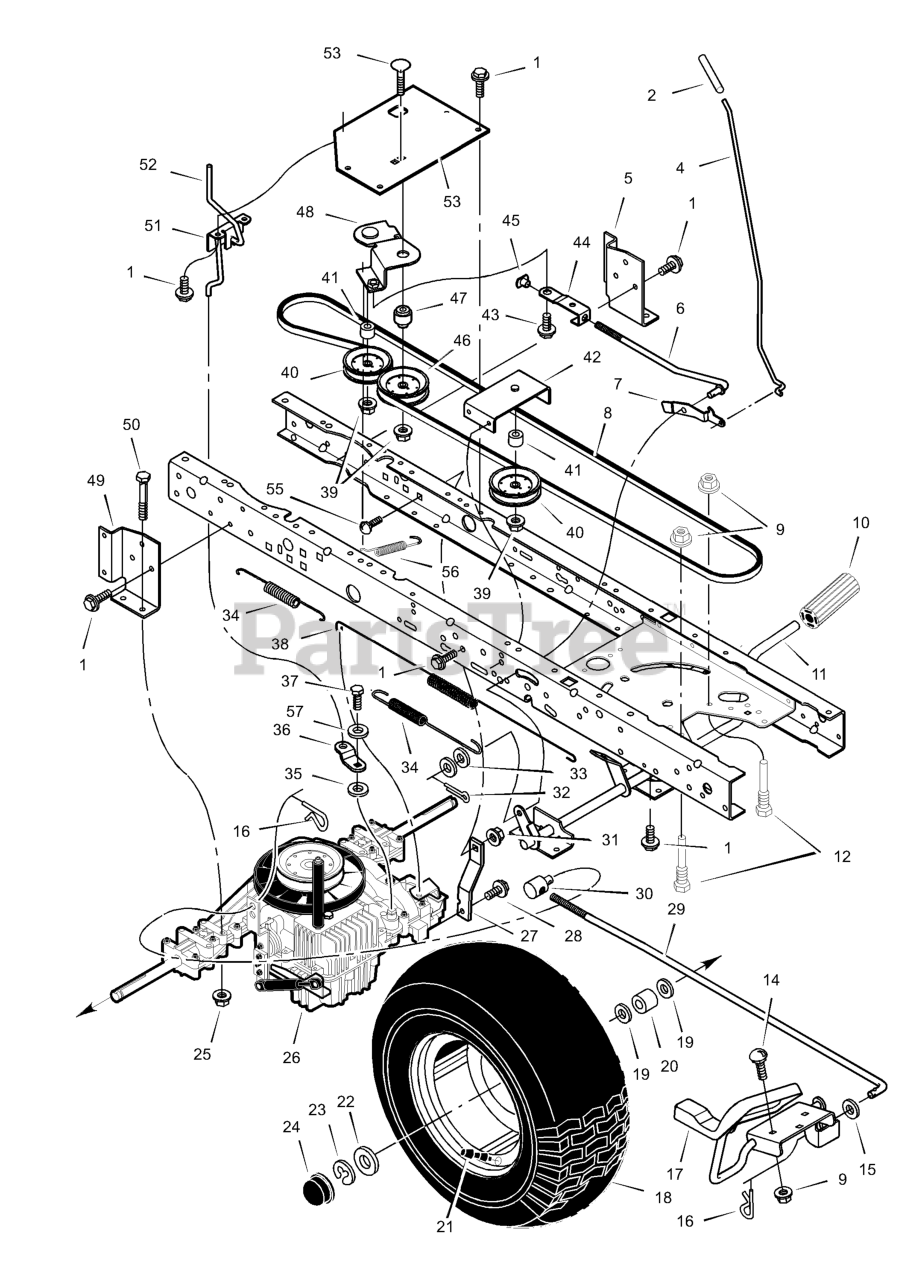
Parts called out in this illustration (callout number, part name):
2	Grip, Parking Brake
4	Rod, Parking Brake
5	Bracket, Left Transaxle
6	Rod, Clutch
7	Latch, Parking Brake
8	V-Belt, Drive
9	Nut, Flange
10	Pedal, Brake/Clutch
11	Assembly, Brake Pedal
12	Screw, Guide
14	Bolt, Carriage
16	Pin, Hair
17	Pedal Assembly, Hydro
18	Wheel & Tire Ass'y, Rear
20	Spacer
21	Stem, Valve
24	Cap, Hub
25	Nut, Centerlock
26	Transaxle **
27	Strap, Torque
29	Rod, Control
30	NUT, Adjusting, 1/2-13
31	Nut, Centerlock
32	Pin, Cotter
34	Spring, Extension
36	ARM, Disconnect
37	Capscrew
38	Spring, Brake
39	Locknut, Flange
40	Pulley, Idler
42	Bracket, Idler Assembly
43	Bolt, Shoulder
44	Link, Clutch
45	Nut, Tee
46	Pulley, Idler
47	Bushing, Pivot
48	Arm Assembly, Idler
49	Bracket, Right Transaxle
50	Bolt, Hex
51	Bracket, Disconnect
52	Rod, Disconnect
53	Bracket, Idler Pivot
54	Bolt, Carriage
55	Bolt, Carriage
56	Spring, Clutch
